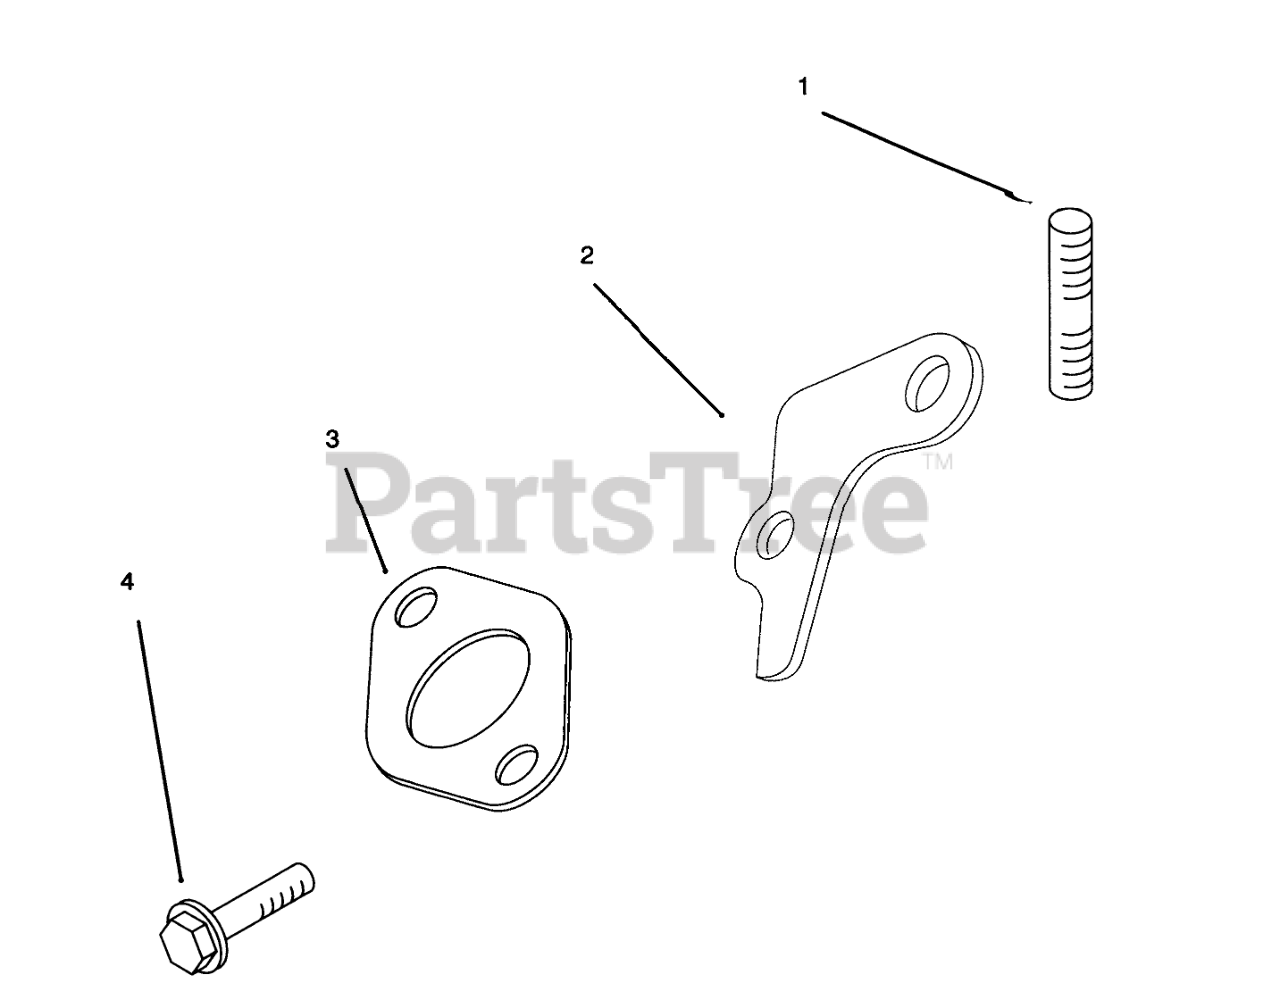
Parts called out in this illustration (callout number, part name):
1	Stud
2	Stra-Lifting
3	Gasket-Exhaust
4	Screw
